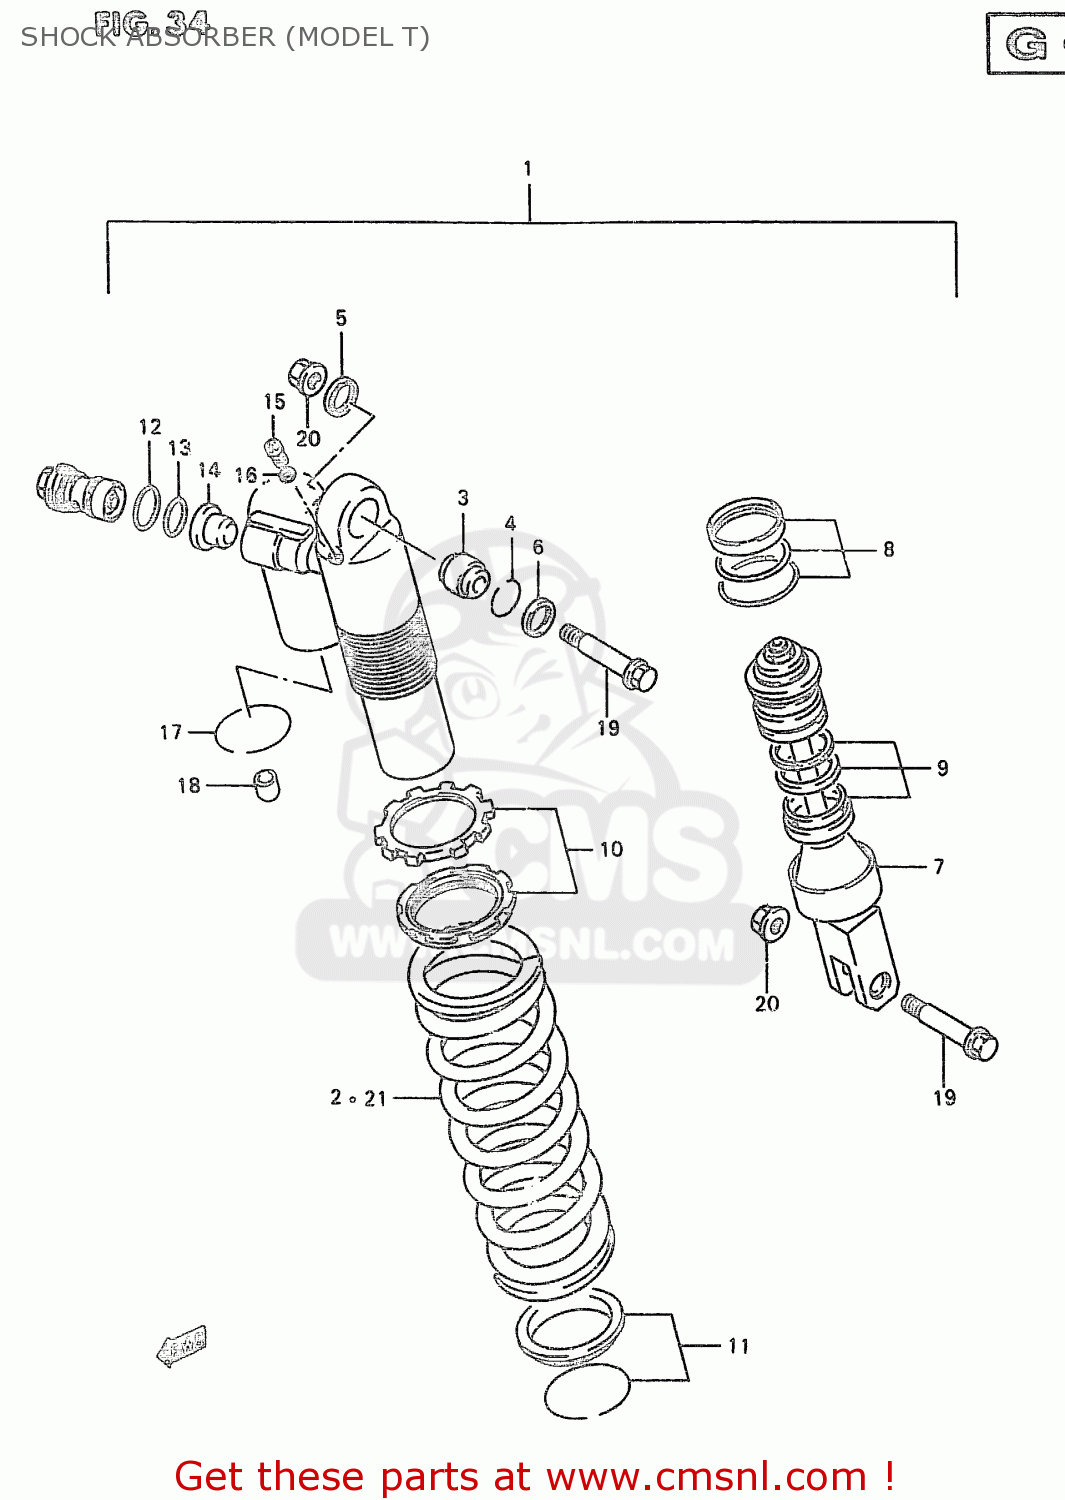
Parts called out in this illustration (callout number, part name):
1	ABSORBER ASSEMBLY,REAR SHOCK
2	SPRING,REAR (K=5.0)
3	BEARING,RR SHOCK ABSORBER
4	RING,STOPPER
5	SEAL,DUST UPR,R
6	SEAL,DUST UPR,L
7	ROD,PISTON
8	O RINR SET
9	RING STOPPER SET,ABSORBER
10	ADJUSTER SET,SHOCK ABSORBER
11	SPRING SEAT SET,SHOCK ABSORBER
12	O RING
13	O RING,CTR BOLT UPR
14	COLLAR,ORIFICE
15	BOLT
16	GASKET,DRAIN,PLUG (NAS)
17	RING,STOPPER
18	CAP
19	BOLT(10X47.5)
20	NUT
21	SPRING (WHITE)
